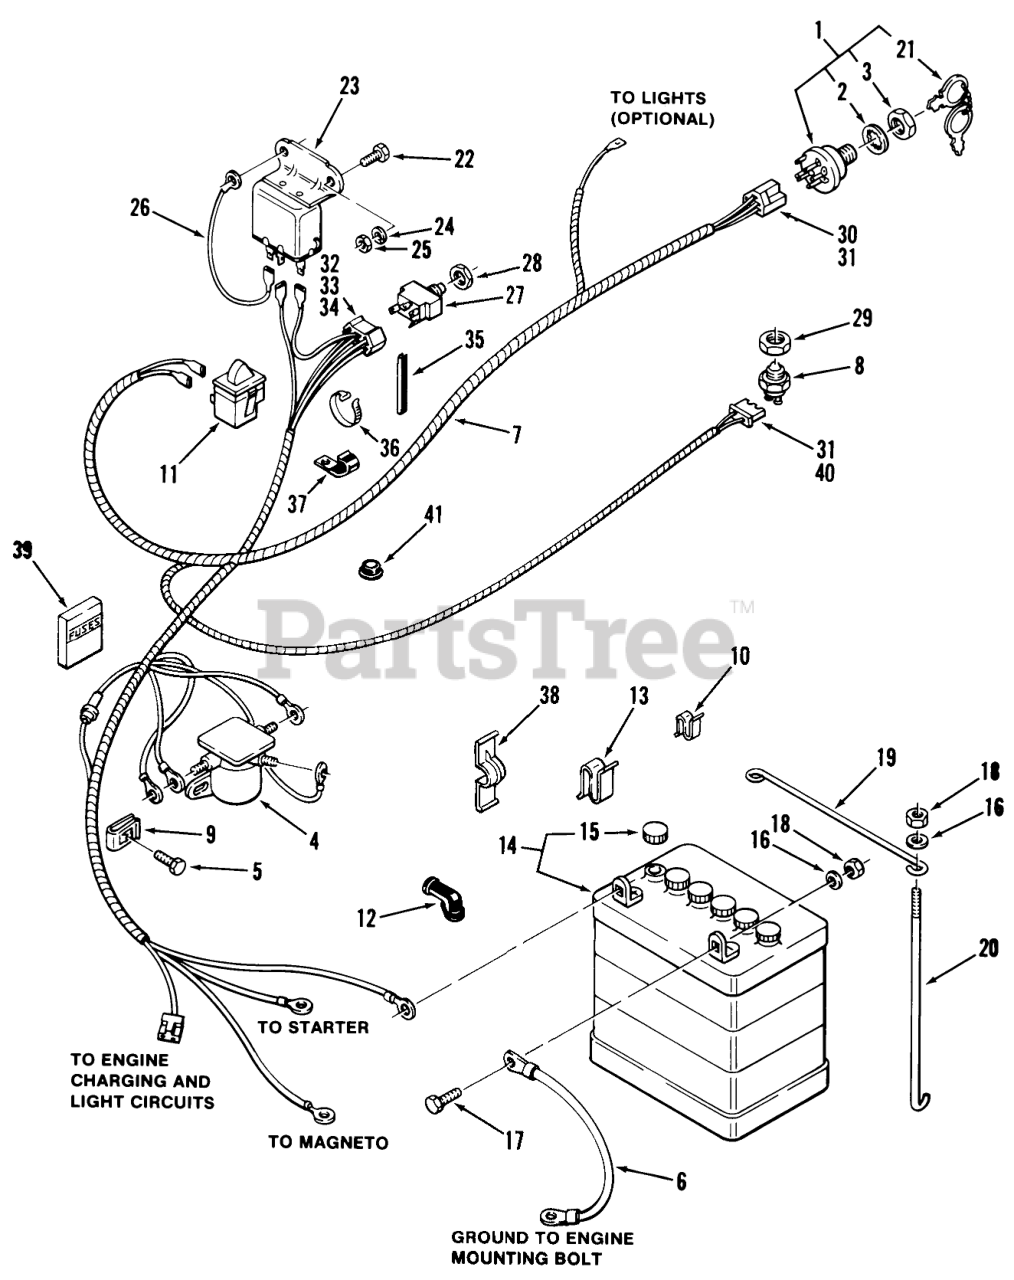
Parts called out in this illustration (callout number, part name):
1	SWITCH-IGNITION
2	LOCKWASHER
4	SOLENOID
5	HEX WASHER HD SCREW
6	Wire
7	WIRING HARNESS
8	SWITCH-INTERLOK CLUT
9	Speed Nut
10	SPEED CLIP
11	SWITCH INTERLOCK
12	Terminal Cover
13	Clip
14	Battery
17	Bolt
18	Nut
19	ROD-HOLD DOWN
20	Hook
21	Key-EL
22	Bolt 10-32 X 5/8
23	Relay
24	Lockwasher
25	Nut
26	RELAY-GROUND WIRE
27	SWITCH-CLUTCH
28	NUT-HEX
29	NUT-SPECIAL 9/16-18
30	CONNECTOR-5 WAY-SERV
31	Terminal
32	CONNECTOR 5 WAY
33	TERMINAL-TAB RCPT
34	Terminal
35	EDGE TRIM 4IN OF 102896
36	Cable Tie
37	CLIP
38	Clip "Stick-On"
40	Connector Housing M
41	BUSHING-NYLON .75
